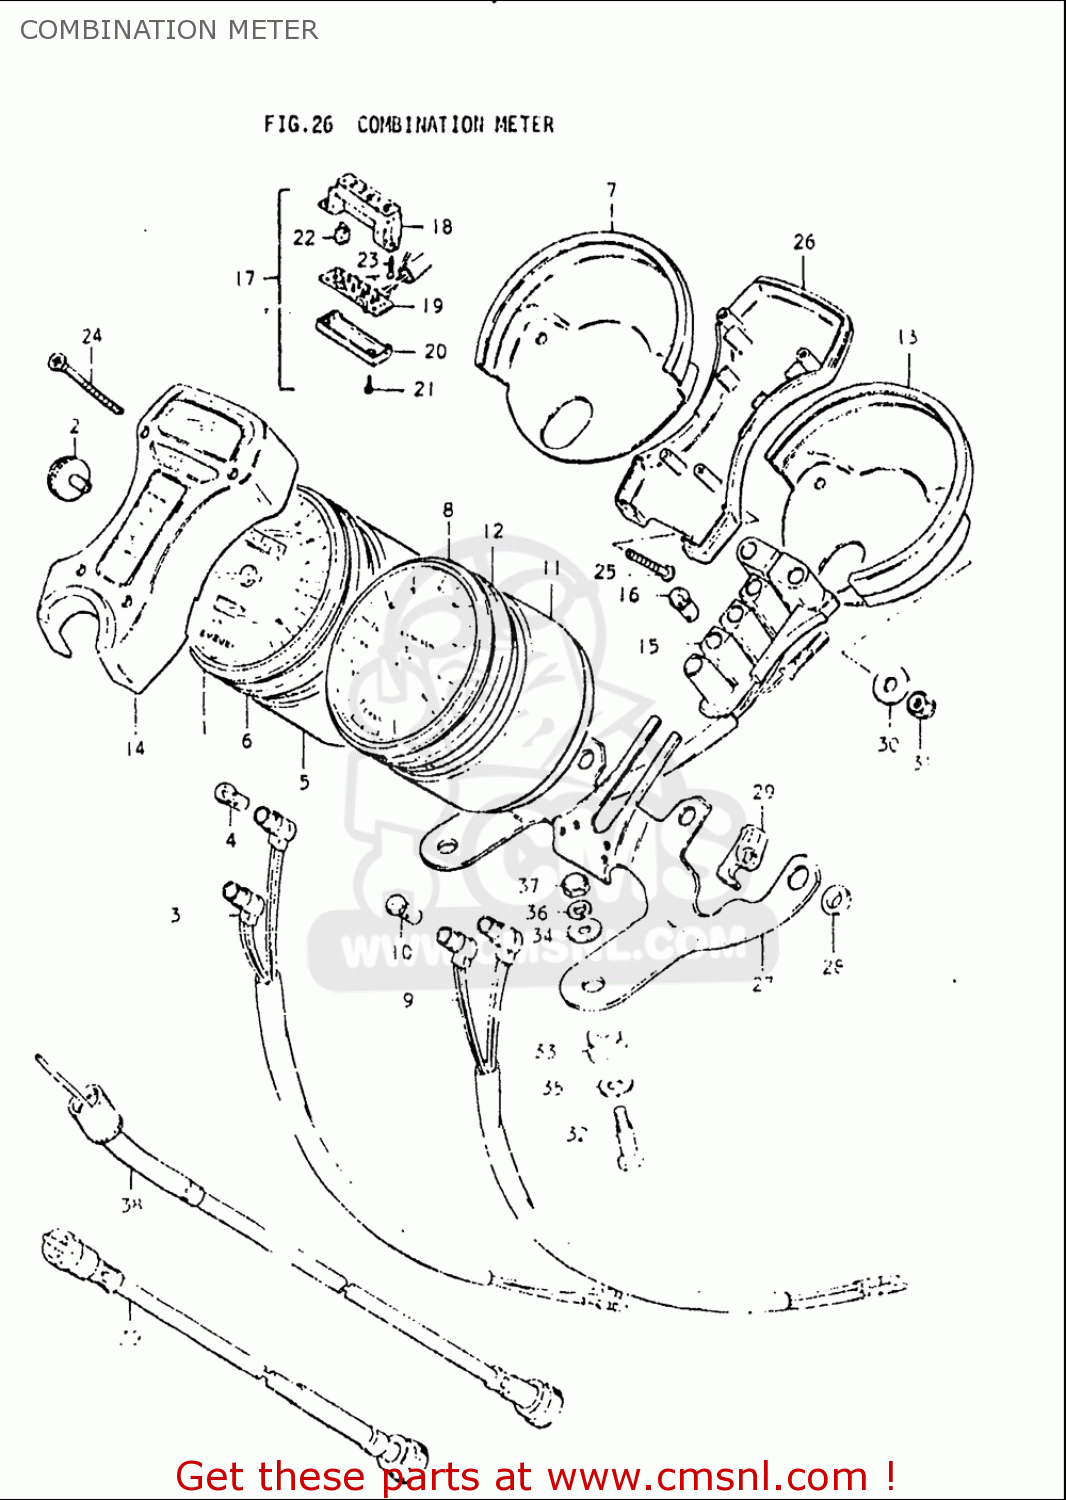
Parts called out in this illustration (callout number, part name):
4	BULB(12V3.4W,STANLEY,A72A)
10	BULB(12V3.4W,STANLEY,A72A)
16	BULB(12V3.4W,STANLEY,A72A)
20	COVER,LWR
21	SCREW
22	BULB(14V1.12W)
24	SCREW
25	SCREW
28	CUSHION,METER (A)
31	NUT
32	BOLT(8X31)
33	CUSHION,METER BRACKET
34	WASHER(8.5X24X1.6)
35	WASHER(10.5X28X1.6)
36	WASHER,LOCK
37	NUT
38	CABLE ASSY,SPEEDOMETER
39	CABLE ASSY,TACHOMETER
